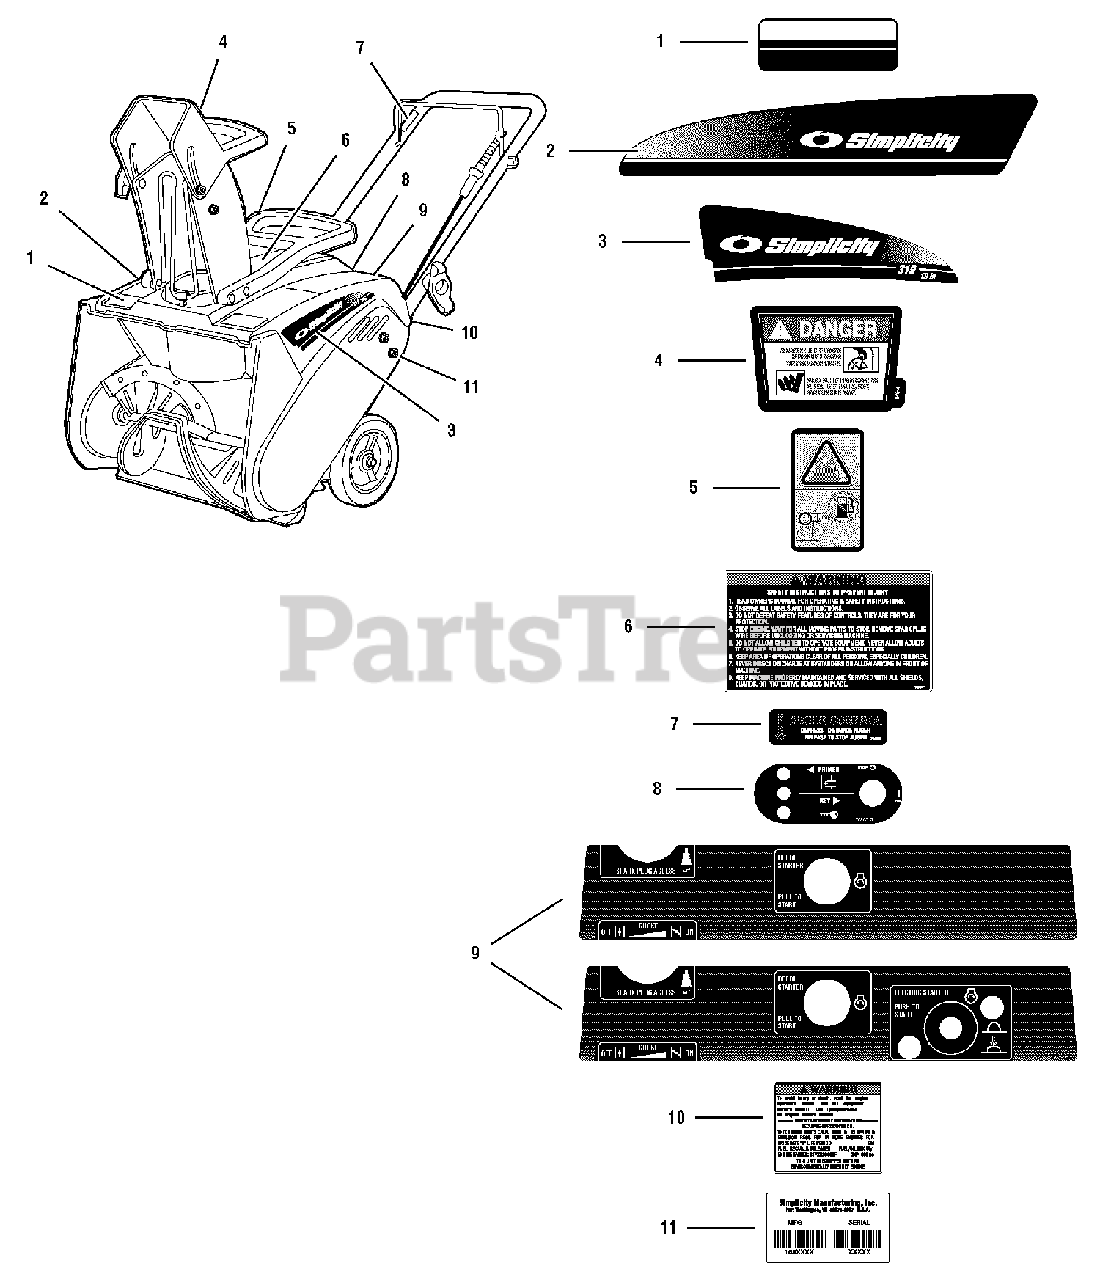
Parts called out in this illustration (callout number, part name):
1	DECAL, Top Cover, Front
2	DECAL, Top Cover, Right Hand
3	DECAL, Top Cover, Left Hand
4	DECAL, Danger Chute Deflector
5	DECAL, Fuel Safety
6	DECAL, Safety Instructions
7	DECAL, Auger Control
8	DECAL, Primer Instruction, Manual Start
8	DECAL, Primer Instruction/Key Switch, Electric Start
9	DECAL, Panel Instruction, Manual Start
9	DECAL, Panel Instruction, Electric Start
10	DECAL, Tecumseh 3HP Carb/EPA Certified
11	I.D. PLATE, Simplicity
12	DECAL, Danger Auger
13	DECAL, Safety Instructions
13	DECAL, Chute Safety
